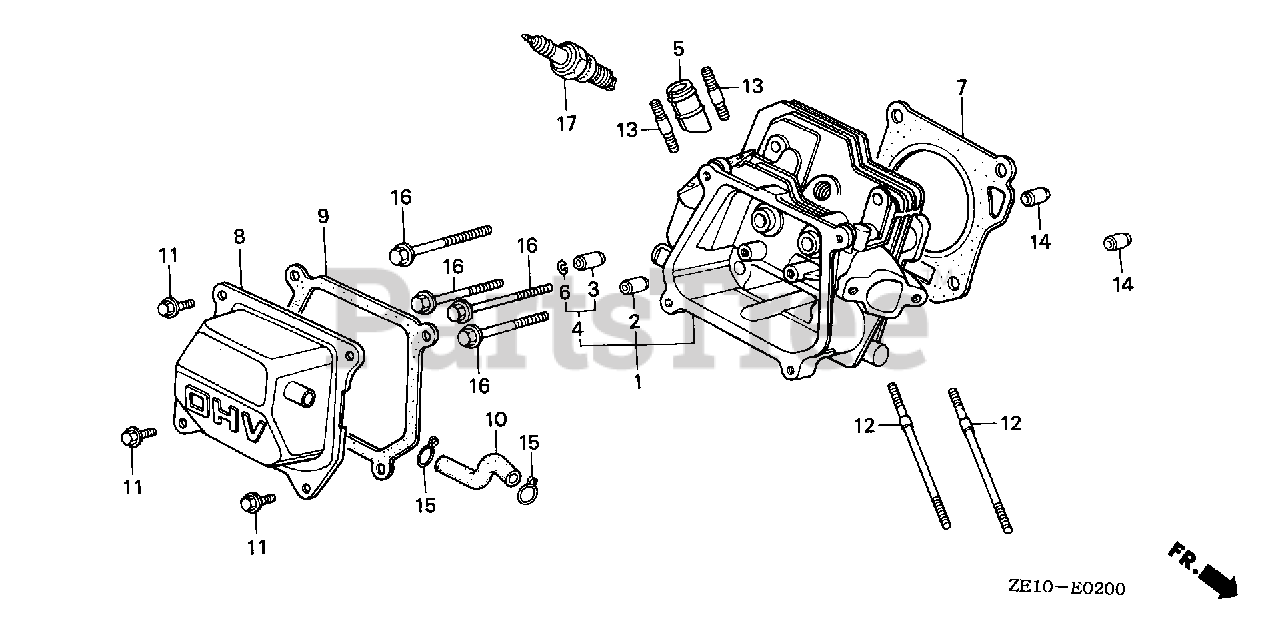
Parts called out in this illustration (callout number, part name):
1	CYLINDER HEAD (NOT AVAILABLE)
1	CYLINDER HEAD
2	GUIDE, VALVE (OVER SIZE)
3	GUIDE, EX. VALVE (OVER SIZE) Use up to Engine SN 1369812.
4	GUIDE, EX. VALVE (OVER SIZE) Use from Engine SN 1369813.
6	CLIP, VALVE GUIDE
7	GASKET, CYLINDER HEAD
8	COVER, HEAD
9	GASKET, HEAD COVER
10	TUBE, BREATHER
11	BOLT, FLANGE (6X12) (CT200)
11	BOLT, FLANGE (6X13) (CT200)
12	BOLT, STUD (6X112)
13	BOLT, STUD (8X32)
14	PIN, DOWEL (10X16)
16	BOLT, FLANGE (8X60)
17	SPARK PLUG (BPR6ES) (NGK)
17	SPARK PLUG (W20EPR-U) (DENSO)
